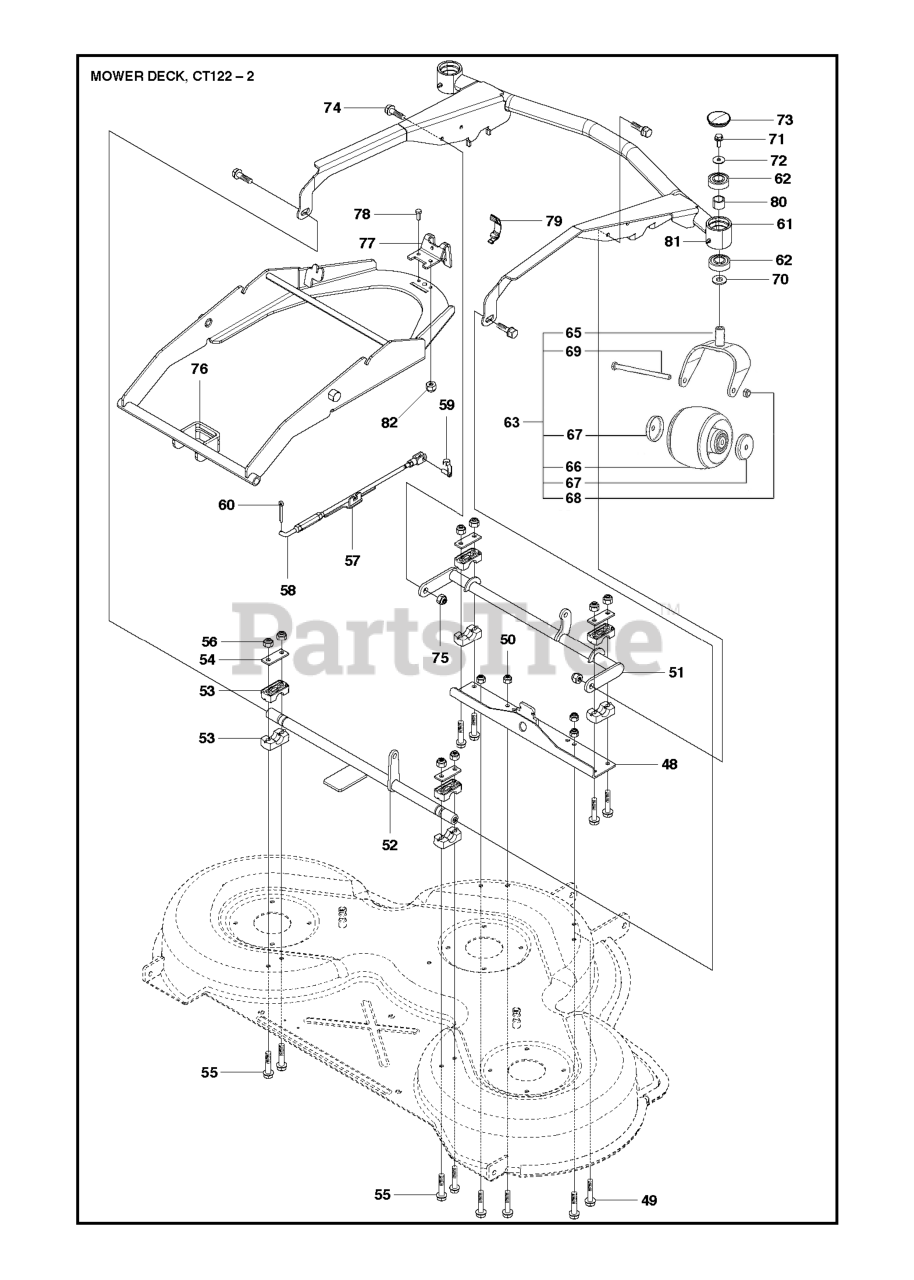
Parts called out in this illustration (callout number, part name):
1	PLUNGER CAP
2	ROD,PARK BRAKE
3	BRKT,PARK BRAKE
4	FOOT PEDAL COVER
5	BRKT,CLU PEDAL LH
6	COTTER PIN
8	Screw 5/16-18 x 1/2 Hex, Self Tapping 5/16-18 x 1/2
9	COTTER PIN
10	WASHER
11	ROD,FRT BRAKE
12	CLUTCH/BRAKE PEDAL ASSY
13	ROD,CLUTCH
14	BRKT,LIFT SHAFT
15	ARM, BRAKE ASMBLY
17	Ring, Klip Truarc #5304-75
18	SPRING, BRAKE ROD
19	NUT
20	NUT
21	ROD REAR BRAKE
22	TRUNNION, LEFT
24	WASHER
25	SPRING TI
26	LOCKNUT
27	LINK.MOWER.REAR
28	REAR MOWER LIFT ASSY
29	BOLT.CARR.SQNK.5/16-18UNC.X3/4
30	NUT
31	SPRING RETAINER
